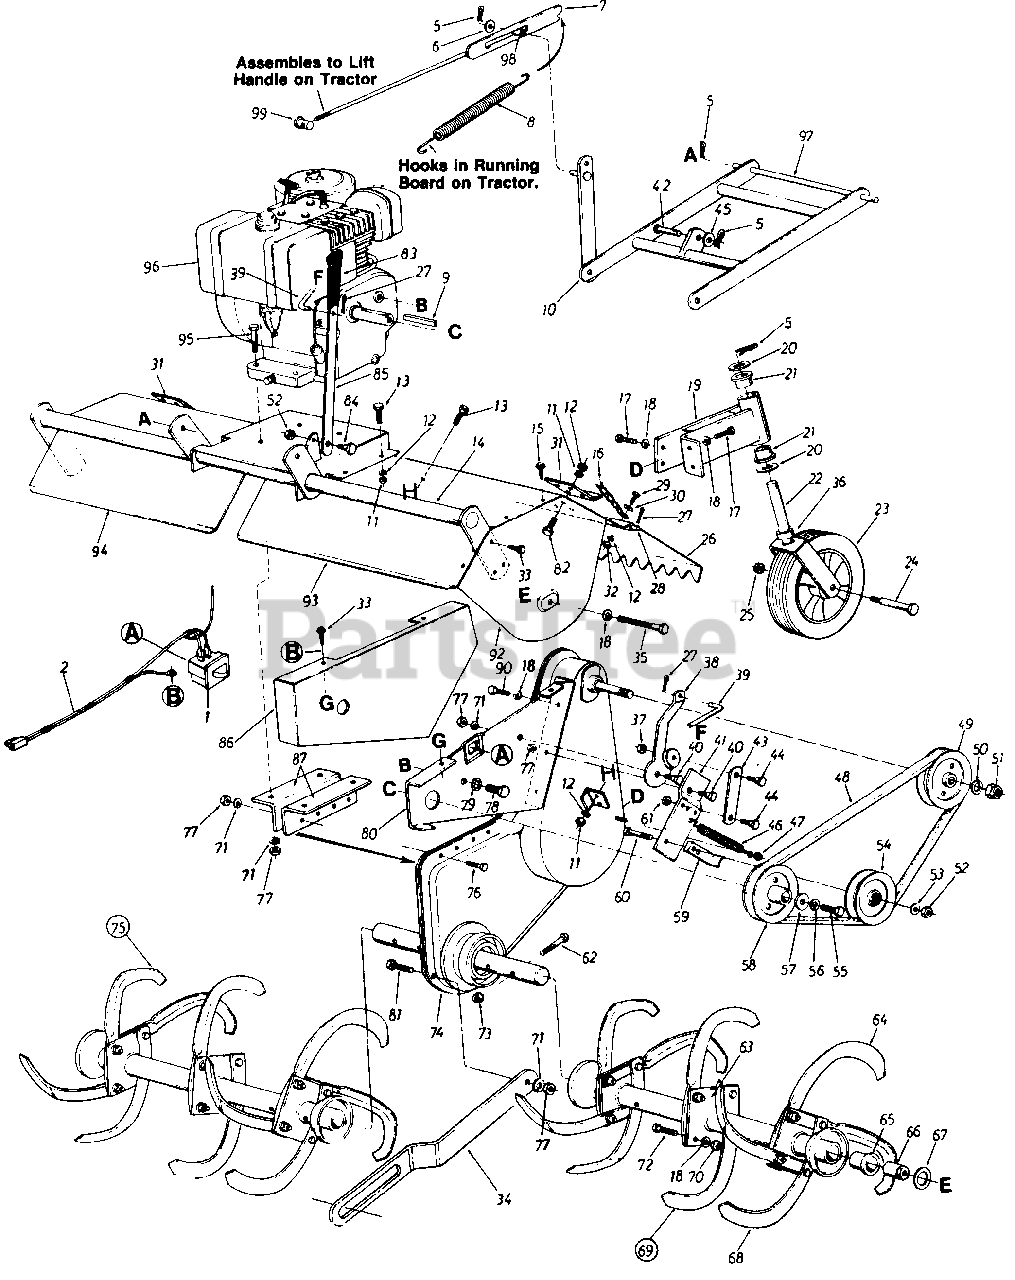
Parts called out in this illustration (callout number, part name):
1	Safety Switch
2	Wire Harness
5	Internal Cotter Pin
6	Fl-Wash. 1/2" I.D. x .93" O.D.
9	Sq. Key l/4" x 1/4" x 200" Lg
12	L-Wash. l/4" l.D.
13	Hex Bolt 1/4-28 x .62 Lg.
16	#2 Dog Chain x 20" Lg.
17	Hex Wash. Hd. Sel-Tap Scr. 3/8-24 x .75" Lg.
18	L-Wash. 3/8n l.D.
21	Flange Bearing 3/4" I.D. x 1.00" OD
24	Shoulder Bolt .623n l.D. x 3.62" Lg.
25	Hex Cent. L-Nut 7/16-14 Thd.
28	L.H Flap Rod
29	Hex Bolt 1/4-20 x .62" Lg.
30	Fl-Wash. 1/4" I.D.
33	Hex Wash. Hd. Selt-Tap Scr. l/4 n x .62" Lg.
36	Spacer.752" l.D. x 1.25" O.D.
37	Hex Cent. L-Nut 5/16-18 Thd.
40	Shoulder Bolt 7/16" Dia. x 1.75 Lg.
41	Idler Bracket
45	Fl-Wash. .50" l.D. x 1.0n O.D. x .06
46	Extension Spring .62" O.D. x 6.12" Lg.
47	Hex Crown Nut 3/8-24 Thd.
48	"V"-Belt (Kevlar)
49	1/2" "V"-Pulley 4.75" O.D. x .625" Bore
50	L-Wash. 5/8" l.D.
51	Hex Ins. L-Nut 5/8-18 Thd.
52	Hex Cent. L-Nut 3/8-16 Thd.
53	Fl-Wash. 3/8" l.D.
54	Idler Pulley 4.0" O.D.
56	L-Wash. 7/16" l.D.
57	Fl-Wash. 7/16" I.D. x 1.38"
58	1/2" "V"-Pulley .475" O.D. x 1.00" Bore
61	Hex Cent. L-Nut 5/16-18 Thd.
62	Hex Bolt 7/16-14 x 2.00 Lg.
67	Thrust Wash. l/2" l.D. x 1.55"
71	L-Wash. 5/16" l.D.
72	Hex Bolt 3/8-24 x 1.5" Lg.
73	Hex Cent. L-Nut 7/16-14 Thd.
77	Hex Nut 5/16-18 Thd.
78	Hex Bolt 1/2-20 x .88 Lg. (Grade 5)
79	L-Wash. 1/2" l.D.
80	Clutch Support Bracket
81	Shld. Bolt .435 Dia. x .265 5/16-t8 Thd.
82	Hex Bolt 1/4-28 x 75n Lg.
83	Plastic Grip
84	Shoulder Bolt .498 Dia. x .212 Lg.
85	Clutch Handle
96	8 H.P. Engine
98	Push Bar Sleeve .503" l.D. x .624 O.D.
